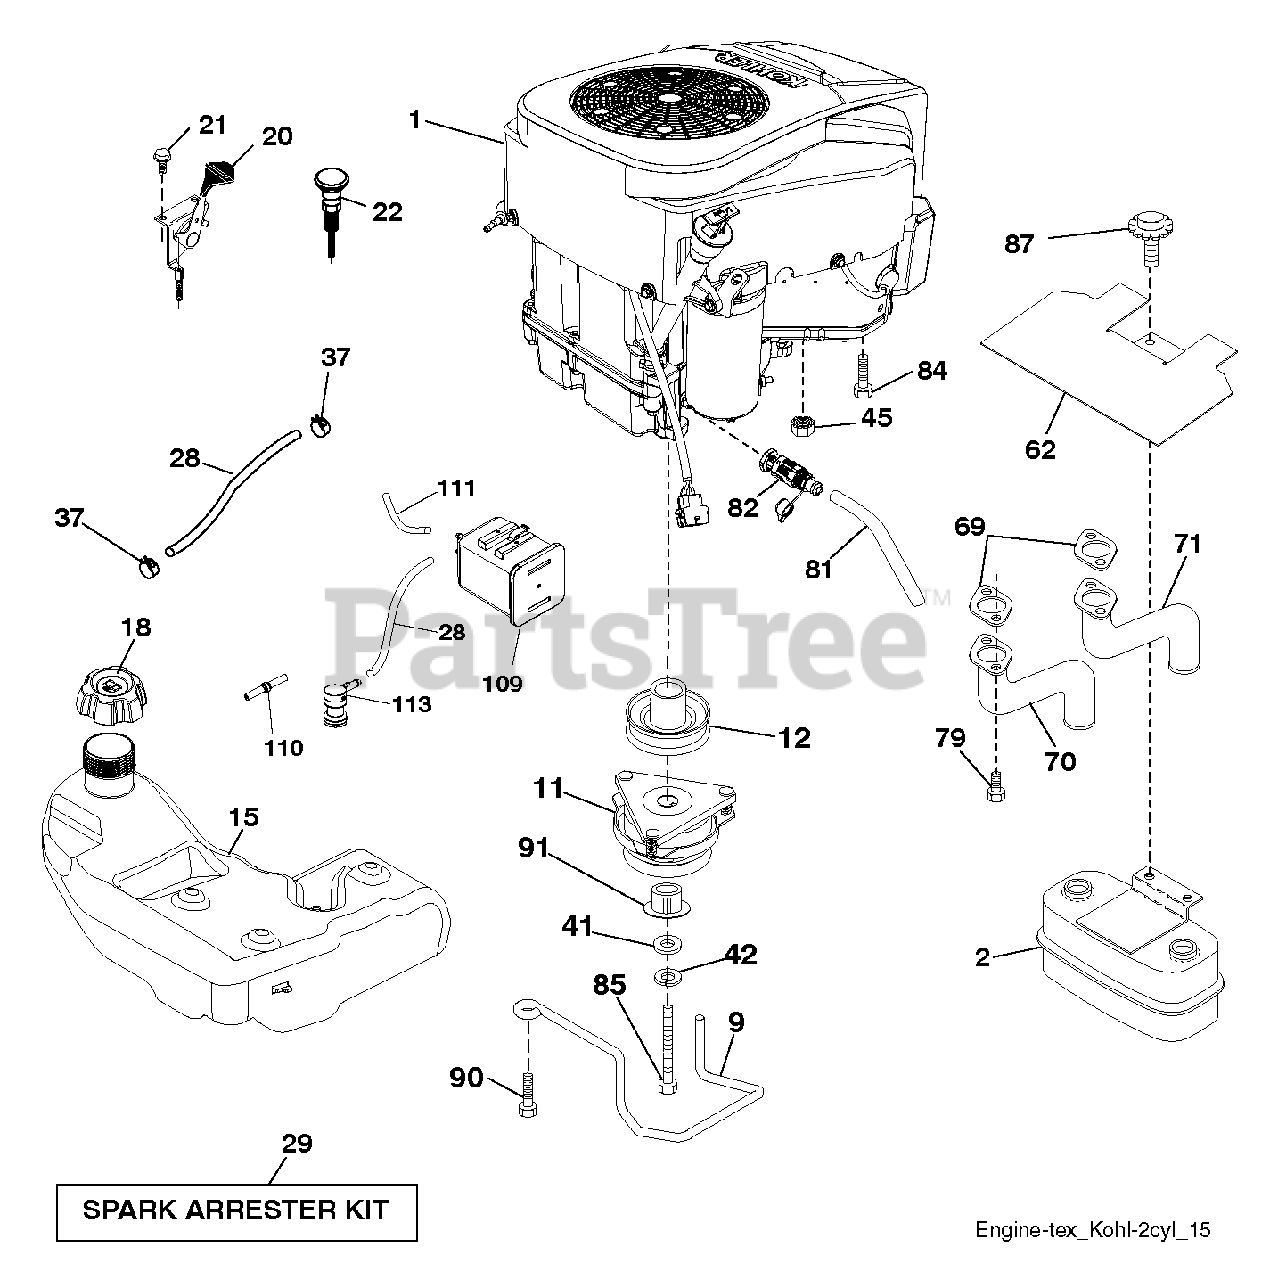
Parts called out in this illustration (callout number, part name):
2	MUFFLER.ASM.TWN.EXTNDED.DFLCTR
9	KEEPER.BELT.ENGINE.4.2
11	CLUTCH MZ ZTR GT.48/54"1.125"
12	PULLEY ENGINE
15	RP TANK.ASM.FUEL.4GA.CARB
18	CAP.ASM.FL.RITCH.3"E10.SYM.498
20	THROTTLE CONTROL
21	SCREW.#10 X 0.750.BOS
22	CONTROL.CHOKE.ERGO.PUSH-IN.BLA
28	LINE.FUEL.64"REAR.EMIS
29	KIT.SPARK ARRESTOR 794945 B&S
37	HOSE CLAMP
42	LOCKWASHER
45	NUT
62	SHIELD.HEAT.MUFFLER
69	GASKET.EXHAUST.KOHL.CV18-CV26
70	RP.PIPE-EXHAUST LH
71	RP.PIPE-EXHAUST RH
79	SCREW.SOCKET HD.5/16-1
81	TUBE, DRAIN OIL ASM.
82	VALUE.OIL.DRAIN
84	SCREW 3/8-16X1
85	BOLT HEX 7/16-20 X 3.75 GR. 5
87	BOLT, 5/16-18 X 1 3/4
90	SCREW 3/8-16X1
91	BUSHING.1.375OD
109	CANNISTER, CARBON
110	VALVE.ASM.ANTI-SLOSH
111	PURGE.LINE.36"REAR.CALIFORNIA
113	VALVE.SLANT.CARTRDG.90 DEG.TEX
